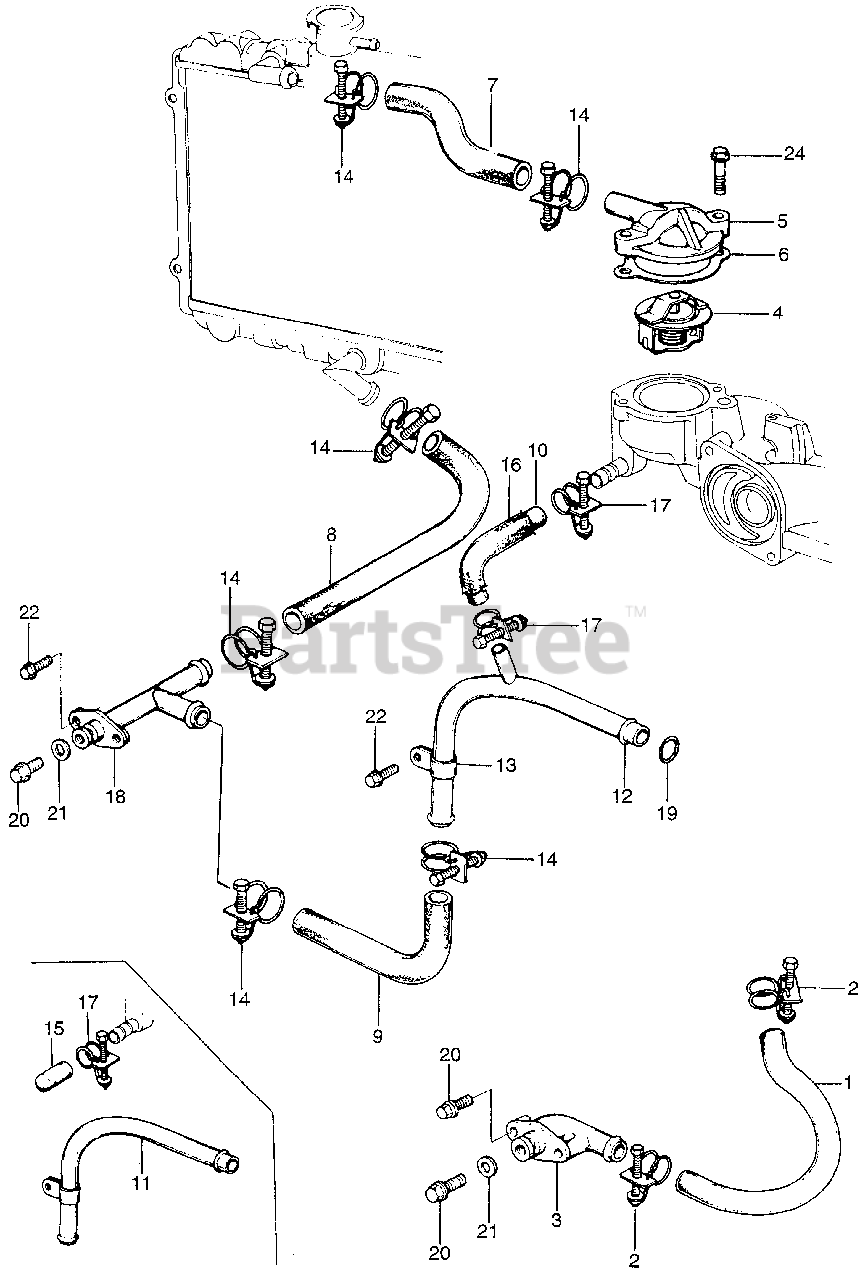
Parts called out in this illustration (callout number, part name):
1	TUBE, OIL DRAIN
2	CLIP, OIL DRAIN HOSE
3	CONNECTOR, OIL DRAIN
4	THERMOSTAT ASSY. (NOT AVAILABLE)
5	COVER, THERMOSTAT
6	COVER, THERMOSTAT
7	HOSE, WATER (UPPER)
8	HOSE, WATER (LOWER)
9	HOSE, WATER
10	HOSE, WATER BYPASS
11	PIPE, CONNECTION
12	PIPE, CONNECTING
13	BAND, CONNECTING PIPE (NOT AVAILABLE)
14	BAND A, PIPE
15	CAP, HEATER PIPE
16	TUBE, BYPASS HOSE
17	CLAMP, WATER HOSE (NOT AVAILABLE)
18	CONNECTOR, WATER TUBE
19	O-RING (24.6X3.2)
20	BOLT, DRAIN PLUG (14MM)
21	WASHER, DRAIN PLUG (14MM)
22	BOLT, FLANGE (6X12)
24	BOLT, FLANGE (6X28)
NI	BOLT, FLANGE (6X16)
